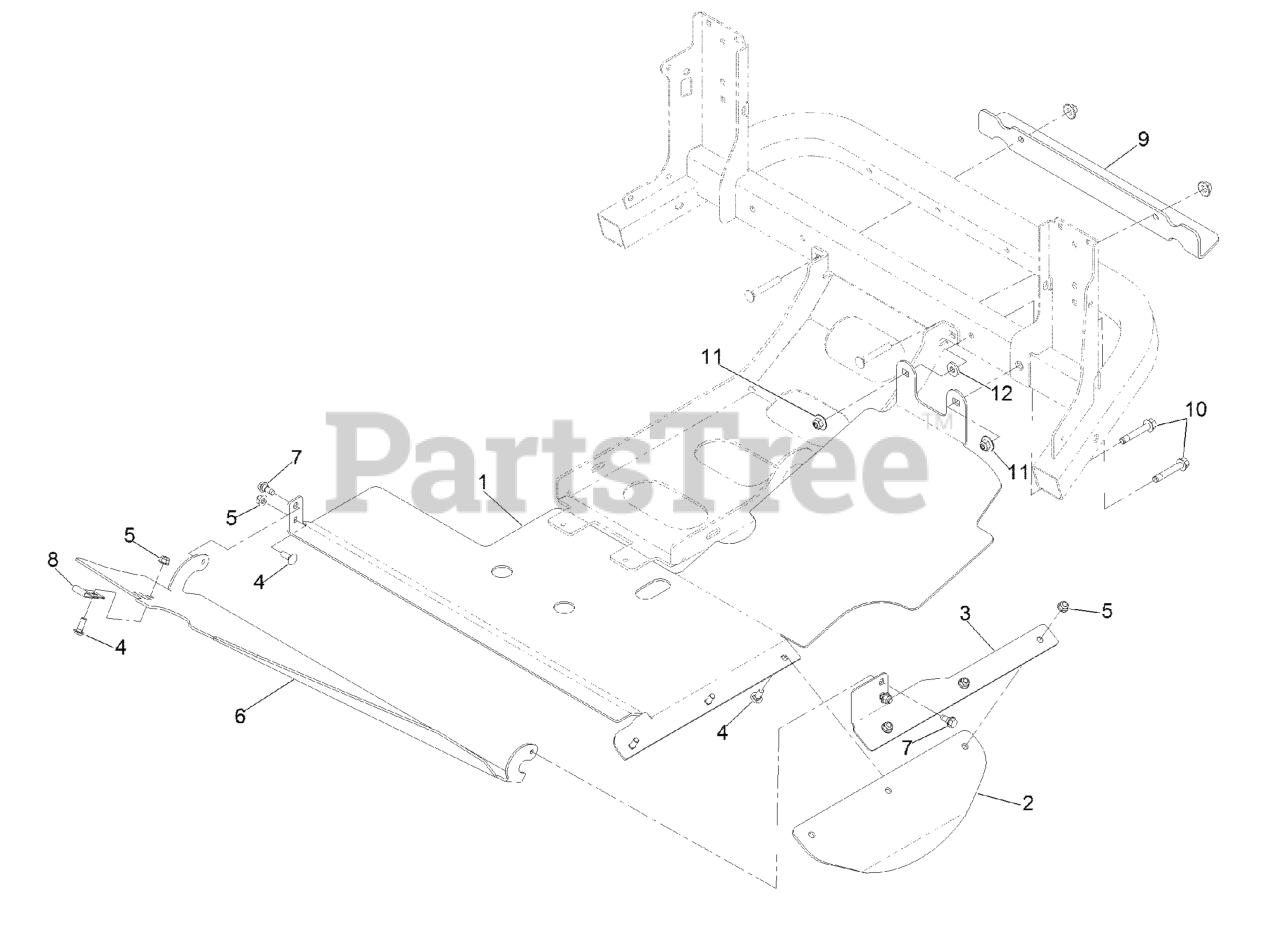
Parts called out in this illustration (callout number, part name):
1	PLATE-DISCHARGE
2	FLAP-RUBBER
3	BRACKET-FLAP, LH
4	SCREW-CARR
5	NUT-HF, NI
6	PANEL-DISCHARGE
7	SCREW-SHOULDER
8	BEARING-STRAP, NYLON
9	BRACKET-TIE DOWN
10	SCREW-HHF
11	Nut-Nyloc 3/8-16 Flg
